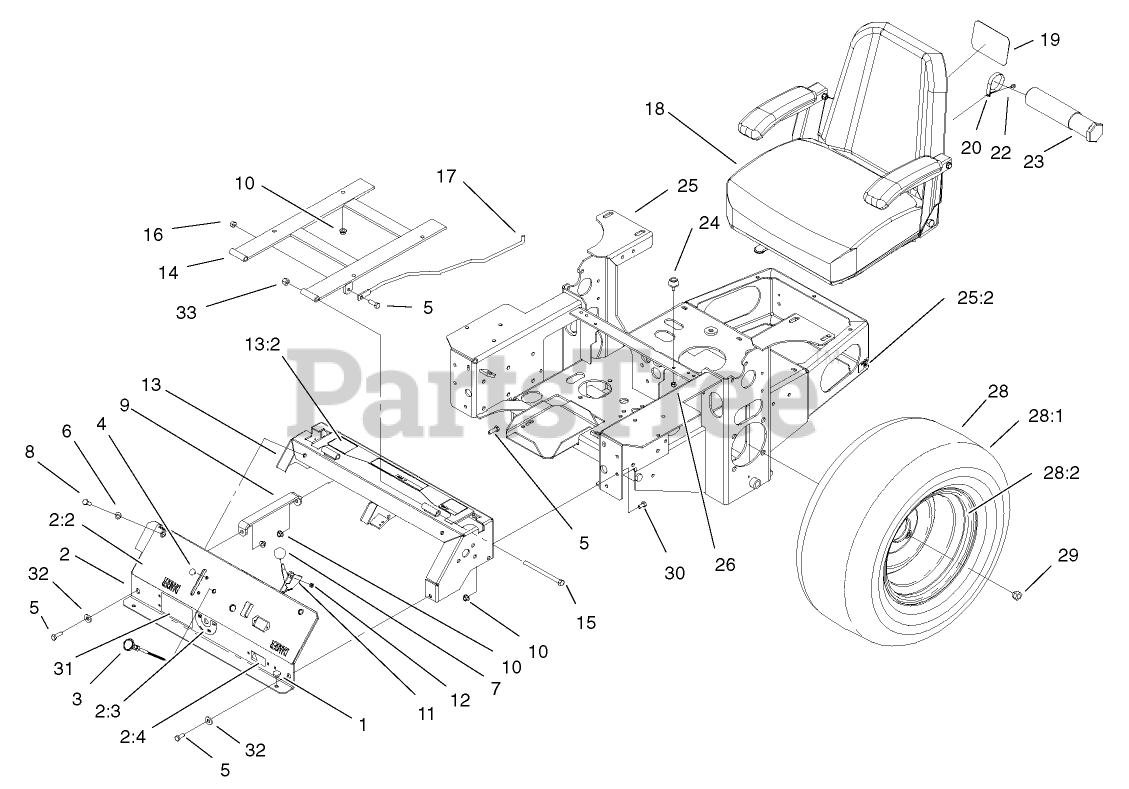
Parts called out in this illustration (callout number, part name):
1	BUMPER
2	CONTROL PANEL ASM
2:2	DECAL-PANEL, CONTROL
2:3	DECAL-VALVE, FUEL
2:4	DECAL-PROTECTION, EAR
3	CONTROL-CHOKE
4	BOLT-CARR
5	SCREW-HH
6	WASHER-PLAIN
7	KNOB-BALL
8	SCREW-HH
9	BRACKET
10	NUT-HF
11	THROTTLE CABLE ASM
12	NUT-LOCK, NI
13	CONSOLE FRAME ASM
13:2	DECAL-CONSOLE, TOP
14	FRAME-SEAT
15	SCREW-HH
16	NUT-LOCK, NI
17	ROD-RETAINER, SEAT
18	SEAT ASM
19	DECAL
20	CLAMP-R
22	SCREW-HWHTF
23	TUBE-MANUAL
24	BUMPER
25	Main Frame ASM
25:2	DECAL-SURFACE, HOT
26	NUT-LOCK, NI
28	WHEEL AND TIRE ASM
28:1	TIRE
29	NUT-LUG
30	SCREW-HH
31	DECAL-Z149
32	WASHER-FLAT
33	NUT-LOCK, NI
